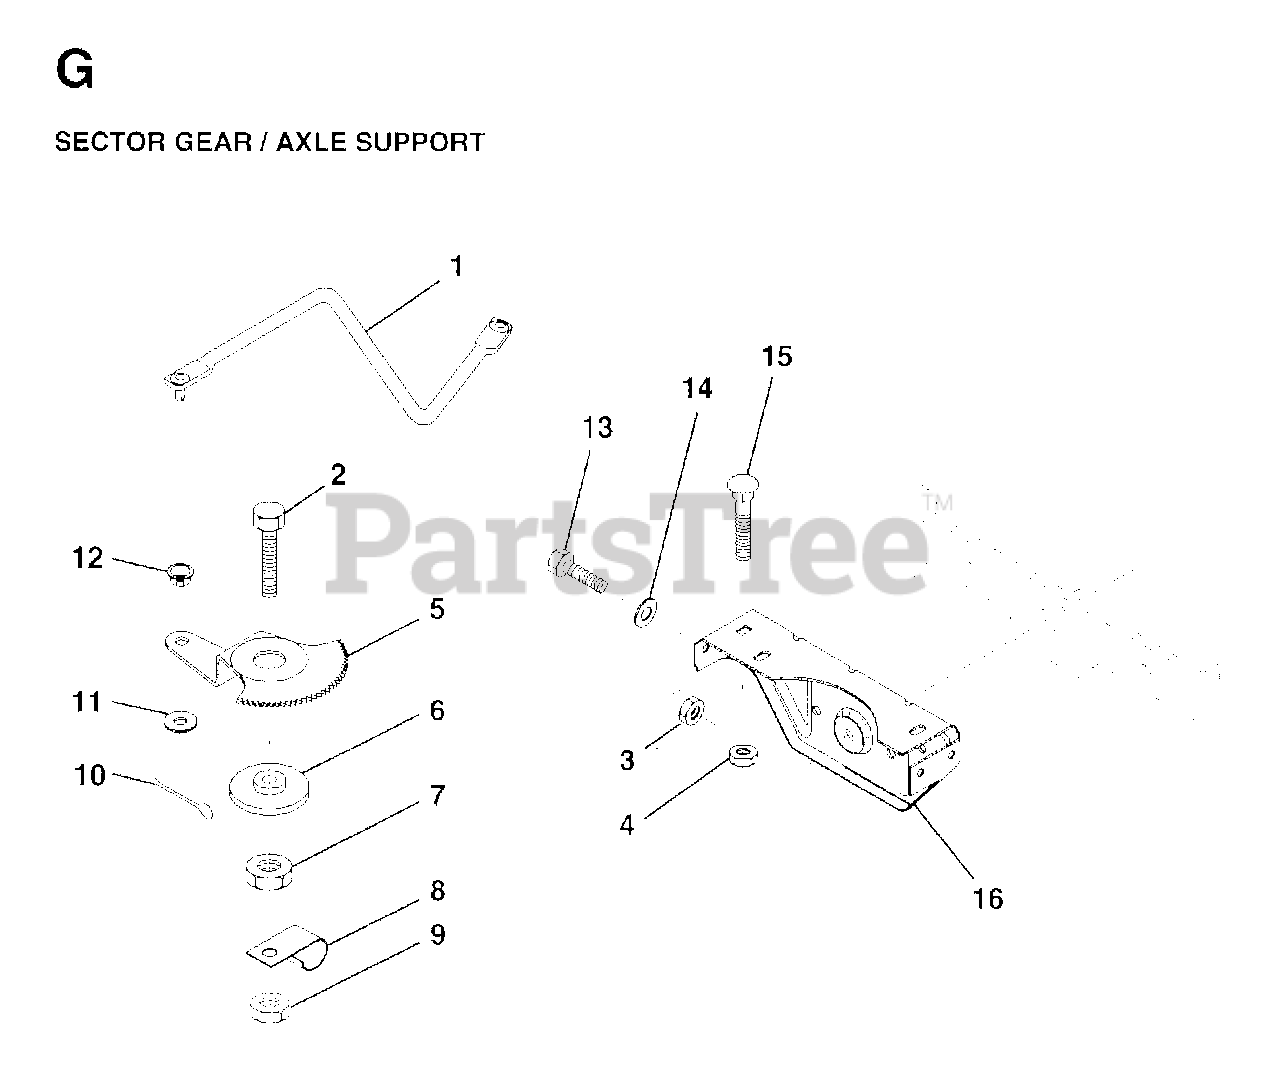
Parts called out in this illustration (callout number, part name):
1	LINK DRAG
3	LOCKNUT
4	LOCKNUT
5	GEAR SECTOR
7	NUT
8	CLIP INSULATOR
9	NUT LTV
10	COTTER PIN
12	BUSHING.DRAGLINK
13	BOLT
14	WASHER
16	SUPPORT/AXLE FRONT
